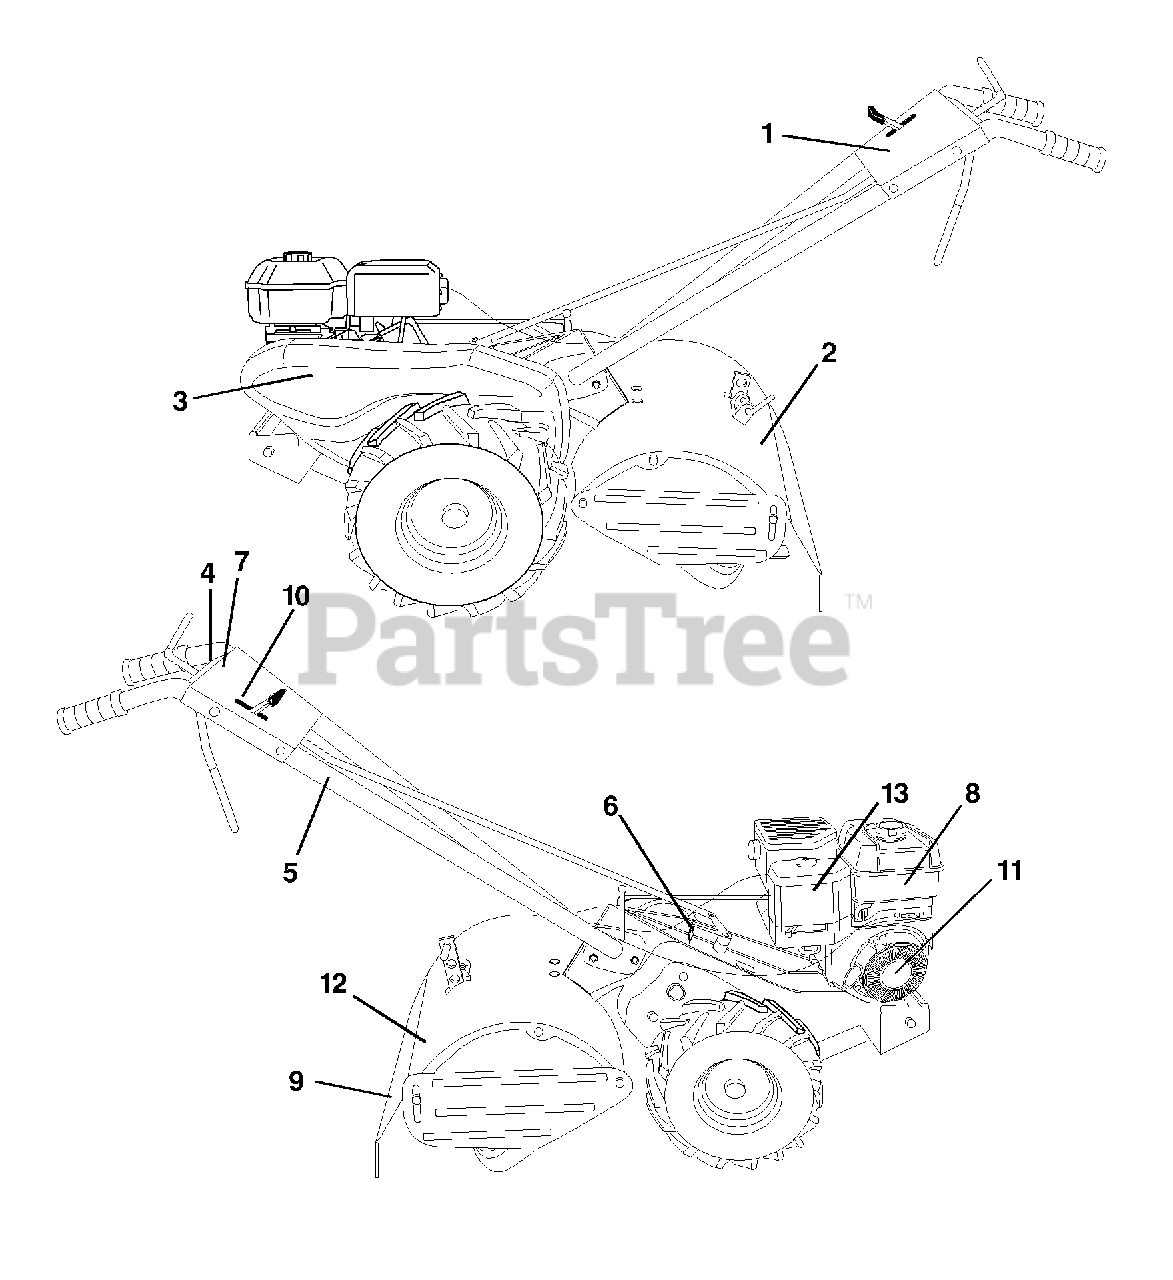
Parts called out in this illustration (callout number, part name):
1	Decal, Logo
2	Decal, Logo
3	Decal, Logo
4	Decal, Instruction, Tilling
5	Decal, Hand Placement
6	Decal, Shift Indicator
7	Decal, Pnl Cntrl Reverse
8	Decal, OHV.N-I/C
9	Decal, Warning, Rotating Tines
10	Decal, Throttle
11	Decal, Rewind Intek
12	Decal, Warning Till
13	Decal, B&S Tiller
